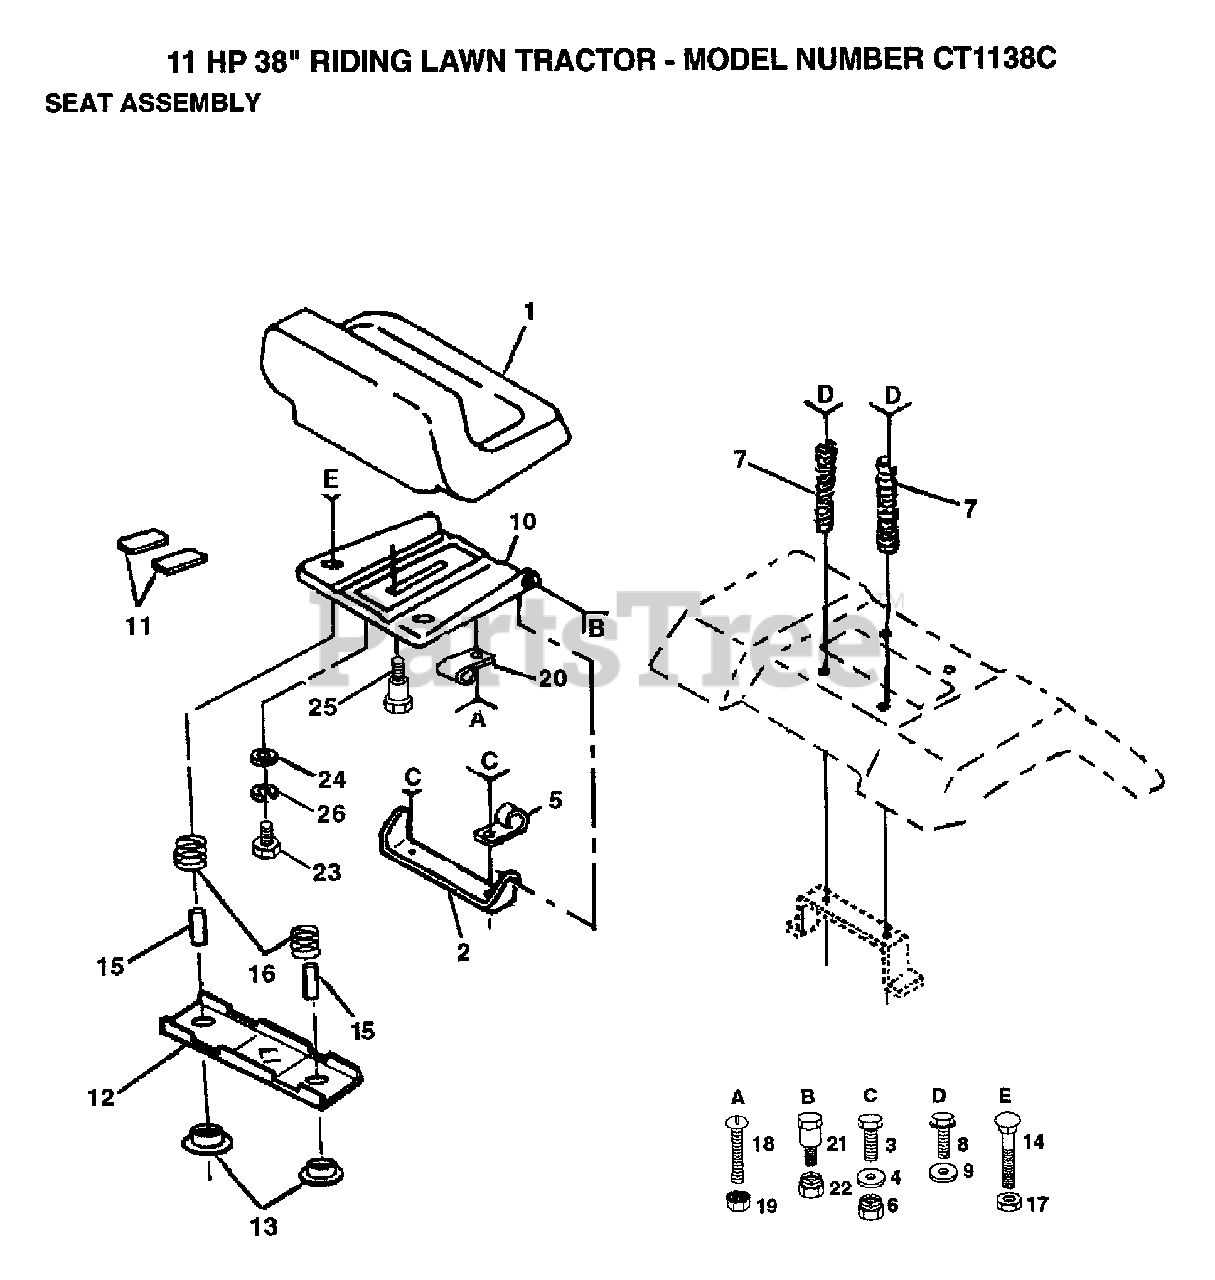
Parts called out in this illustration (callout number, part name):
4	WASHER
5	CLIP T
7	SPRING COMPRESSIO
8	SCREW GTV
9	WASHER
11	STRIP FORM
12	BRKT SWITCH
13	BUSHING
15	SPACER SPLIT
16	SPRING
19	"NUT,KEPS"
23	BOLT
24	WASHER
25	"BOLT,SHOULDER"
26	LOCKWASHER
